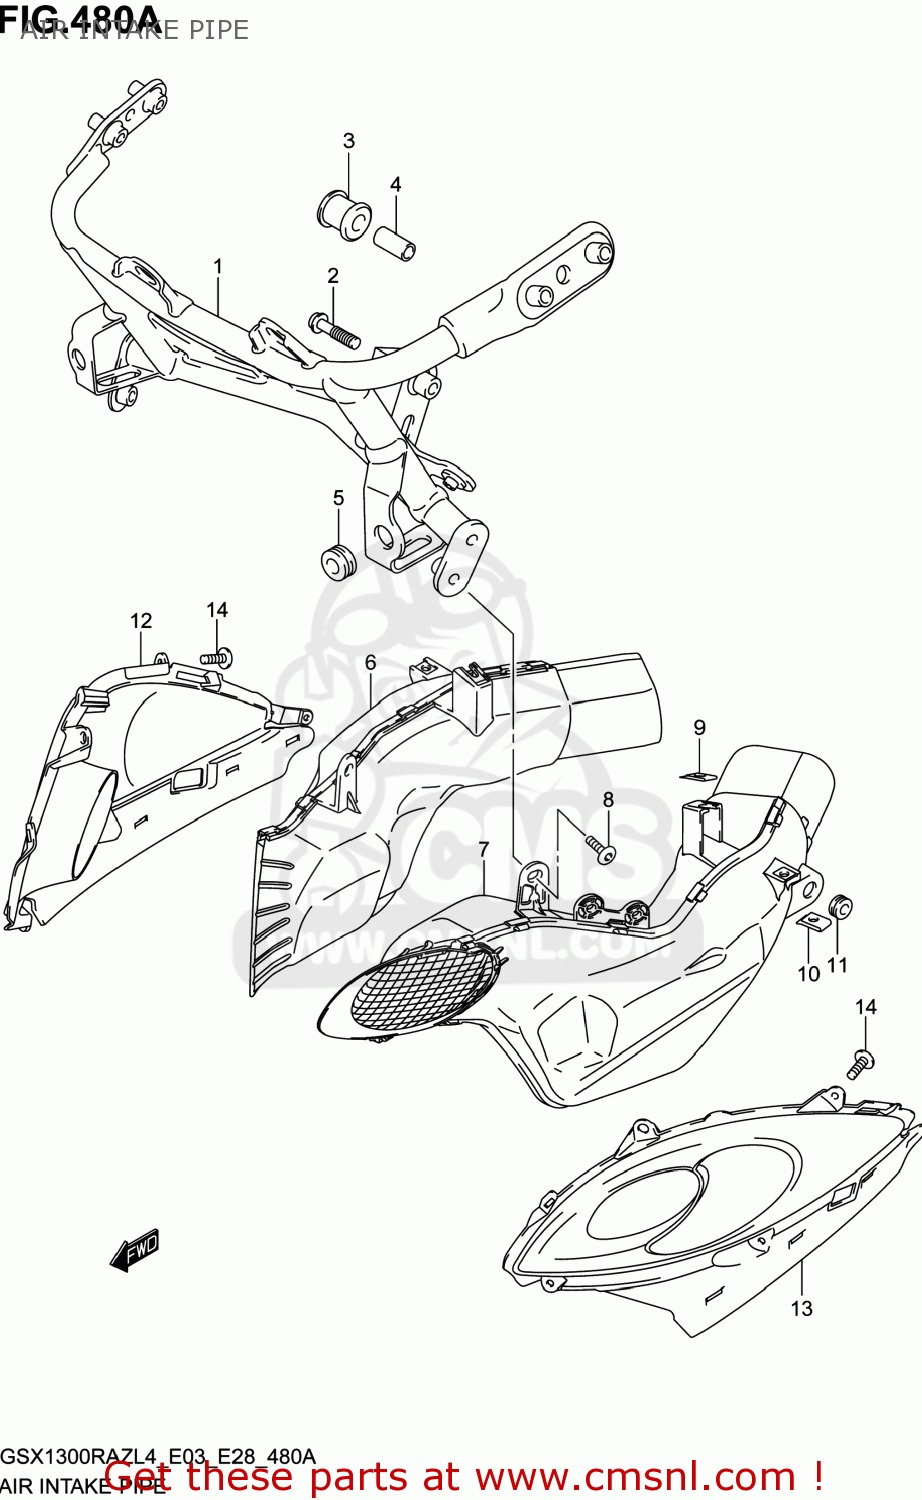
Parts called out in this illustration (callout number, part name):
1	BRACE,COWLING
2	BOLT(8X40)
3	CUSHION,COWLING BRACE
4	SPACER(8.6X12.2X26.5)
5	CUSHION
6	PIPE,AIR INTAKE,R
7	PIPE,AIR INTAKE,L
8	SCREW,INTAKE PIPE & BRACE
9	NUT,COWL
10	NUT
11	CUSHION
12	COVER,INTAKE,R
13	COVER,INTAKE,L
14	SCREW(5X16)
